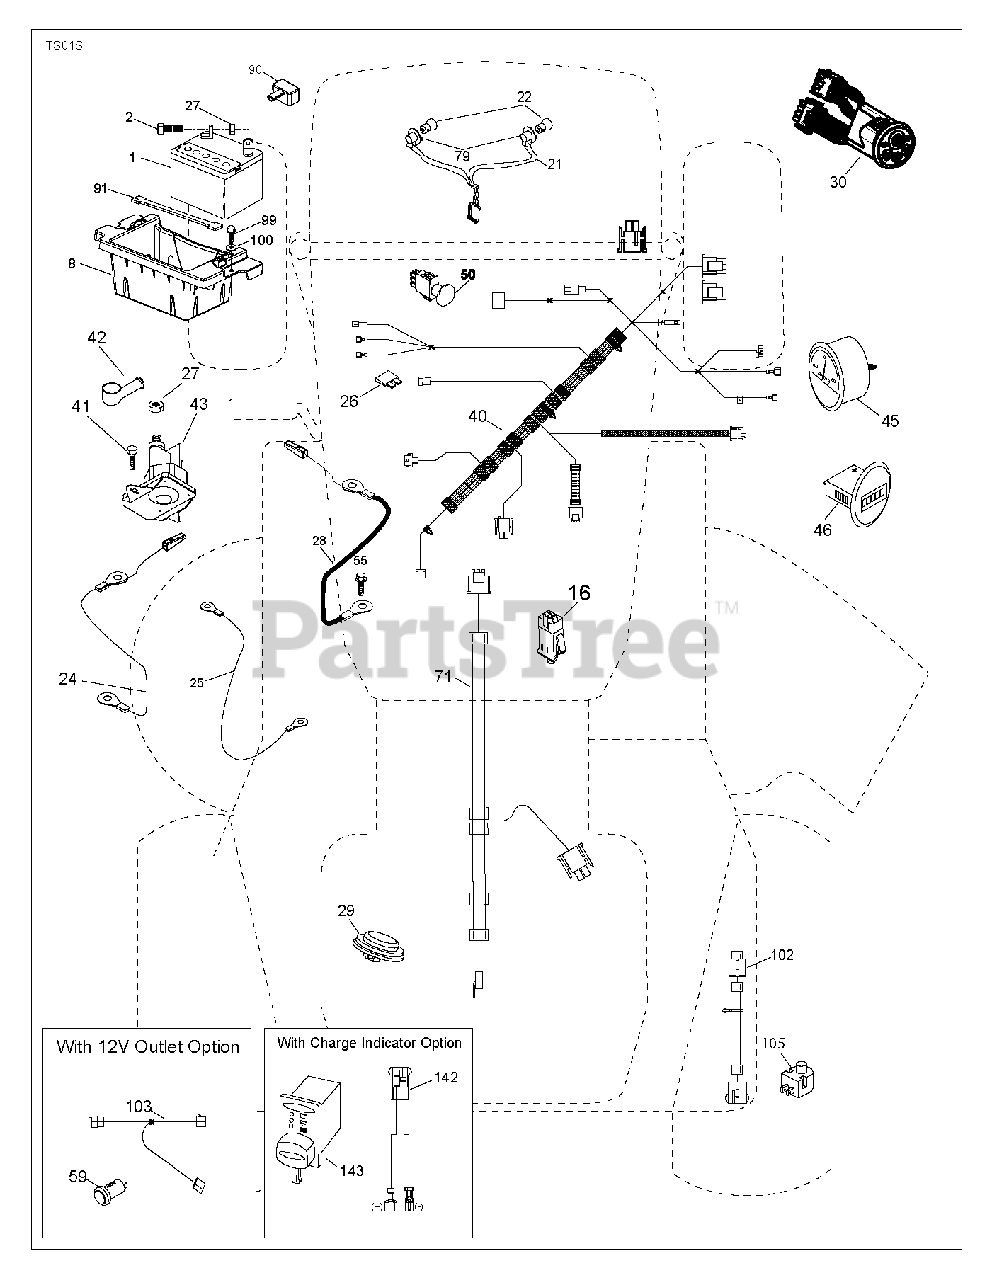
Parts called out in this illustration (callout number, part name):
1	Battery, Dry 30 Amp
2	BOLT.HEX.1/4.X.3/4.DICHROMATE
8	BOX.BATTERY.MOUNT.FRONT.LT
16	SWITCH INTERLOOK PUSH-IN
21	HARNESS.LIGHT W/4152J BULBS
24	CABLE.BTRY.HARN.POS.LEAD
25	CABLE.STARTER.8GA.17.5
26	FUSE 20AMP
27	NUT
28	CABLE.GROUND.STARTER
29	SWITCH.SEAT.OPC.GRY.BUTTON/CAP
30	SMART SWITCH MY14 TRACTOR
40	HARNESS DASH,EL,SIS,RND,FBAT
41	SCREW
42	TERMINAL COVER
43	SOLENOID.W/BRASS.PLUNGER
45	AMMETER GAUGE ROUND SNAP-IN
46	HOURMETER.GAUGE.RNK.SNAPIN.LS
50	RB PTO.SWITCH.8 TERMINAL.BLACK
55	SCREW 5/16"
71	HARNESS.CHAS.TEX.SIS.FBAT.TWIN
79	BULB HOLDER ASM.
90	COVER.TERMINAL.BATTERY
91	STRAP.BATTERY.MOUNT.FRONT(2 2)
99	SCREW HEXWSHR 1/4-20X3/4
102	HARNESS PIGTAIL PCH TEX ROS
105	REVERSE SWITCH
142	CHARGE.PORT.PIGTAIL HARNESS
143	CHARGE.PORT
